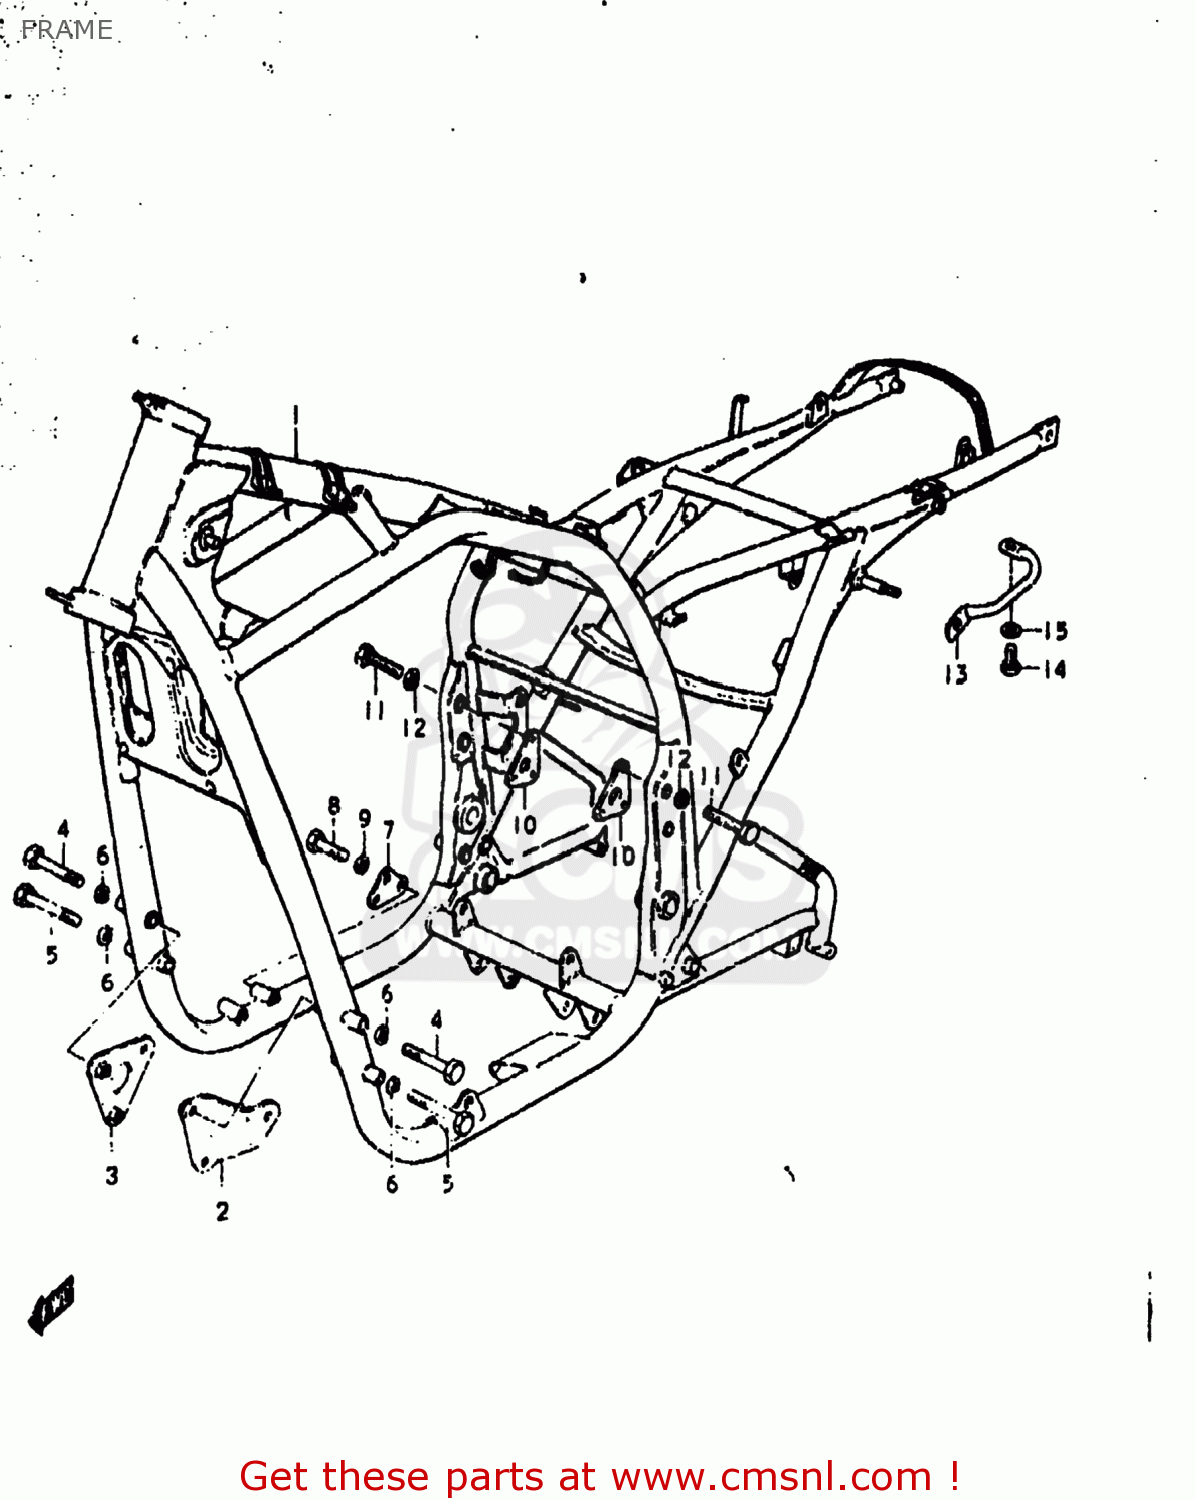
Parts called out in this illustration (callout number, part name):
1	FRAME
2	PLATE,ENGINE MOUNTING
3	PLATE,ENGINE MOUNTING
4	BOLT
5	BOLT
6	LOCK WASHER
7	PLATE,ENGINE MOUNTING
8	BOLT
9	LOCK WASHER
10	PLATE,ENGINE MOUNTING
11	BOLT
12	LOCK WASHER
13	GRIP,FRAME
14	BOLT
15	WASHER
